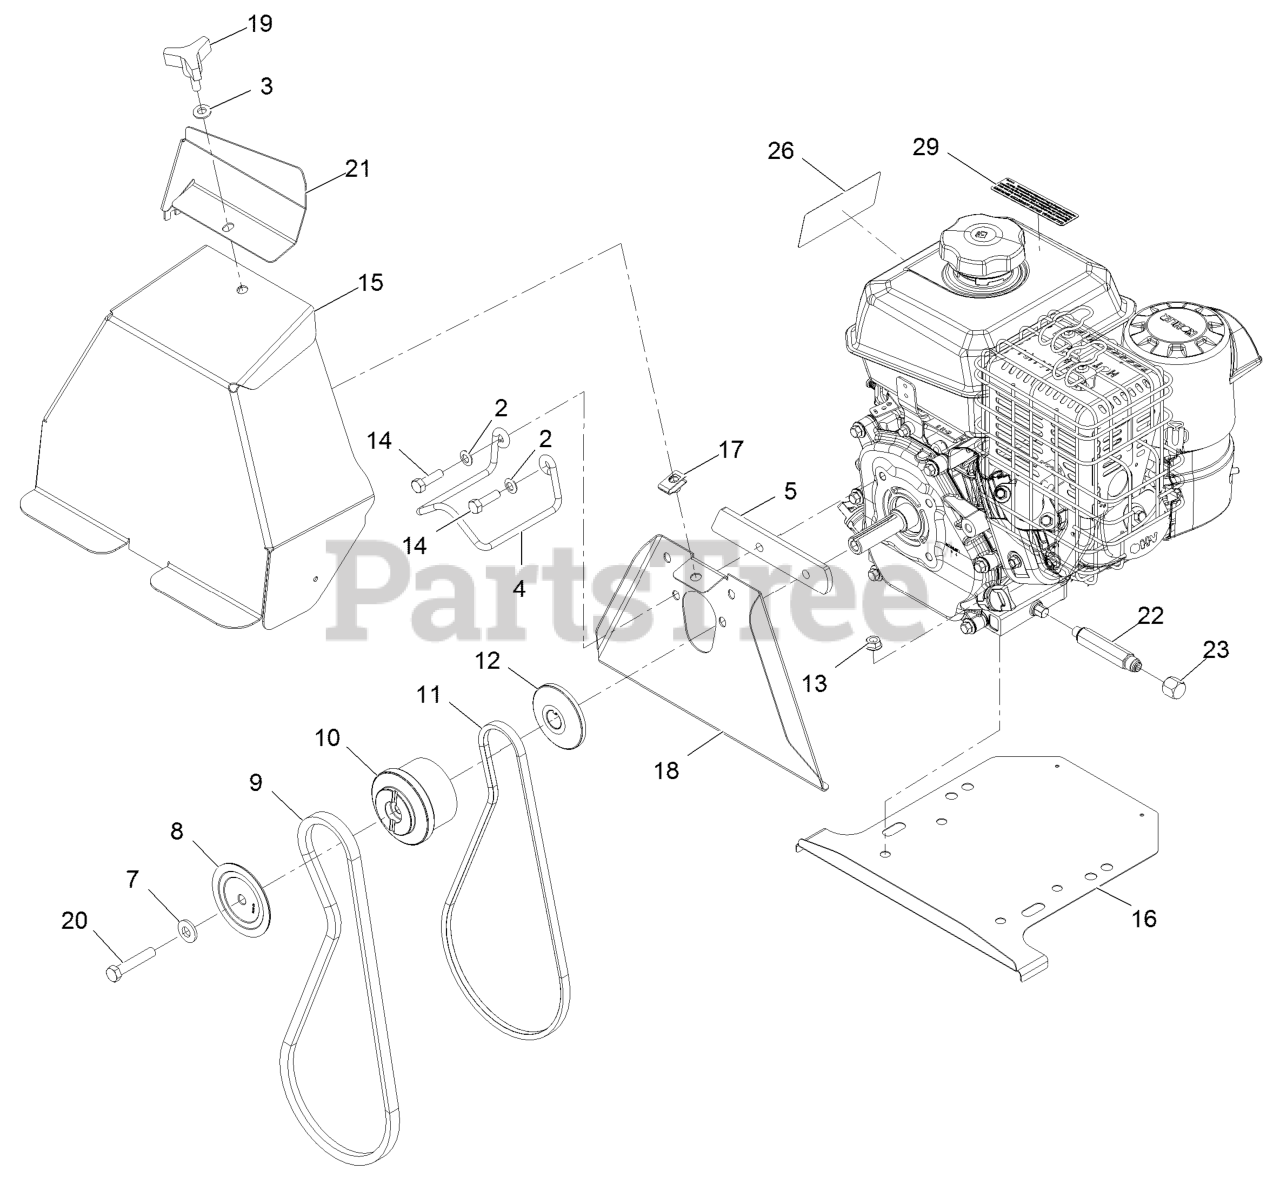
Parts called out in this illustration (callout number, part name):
2	WASHER-BELLEVILLE
3	WASHER-SPRING
5	SPACER-COVER, BELT
7	WASHER-BELLEVILLE
8	SHEAVE-HALF, IMPELLER
9	BELT-BLOWER
10	PULLEY-ENGINE, CENTER
11	V BELT-TRACTION
12	SHEAVE-HALF, TRACTION
14	SCREW-HH
15	COVER - BELT
16	SHIELD-DRIVE
18	COVER-BELT, BACK
20	SCREW-HH
21	SHIELD-ICE, KC CH270
22	ADAPTER
26	Decal-Engine Fuel
29	DECAL-ARRESTER, SPARK
